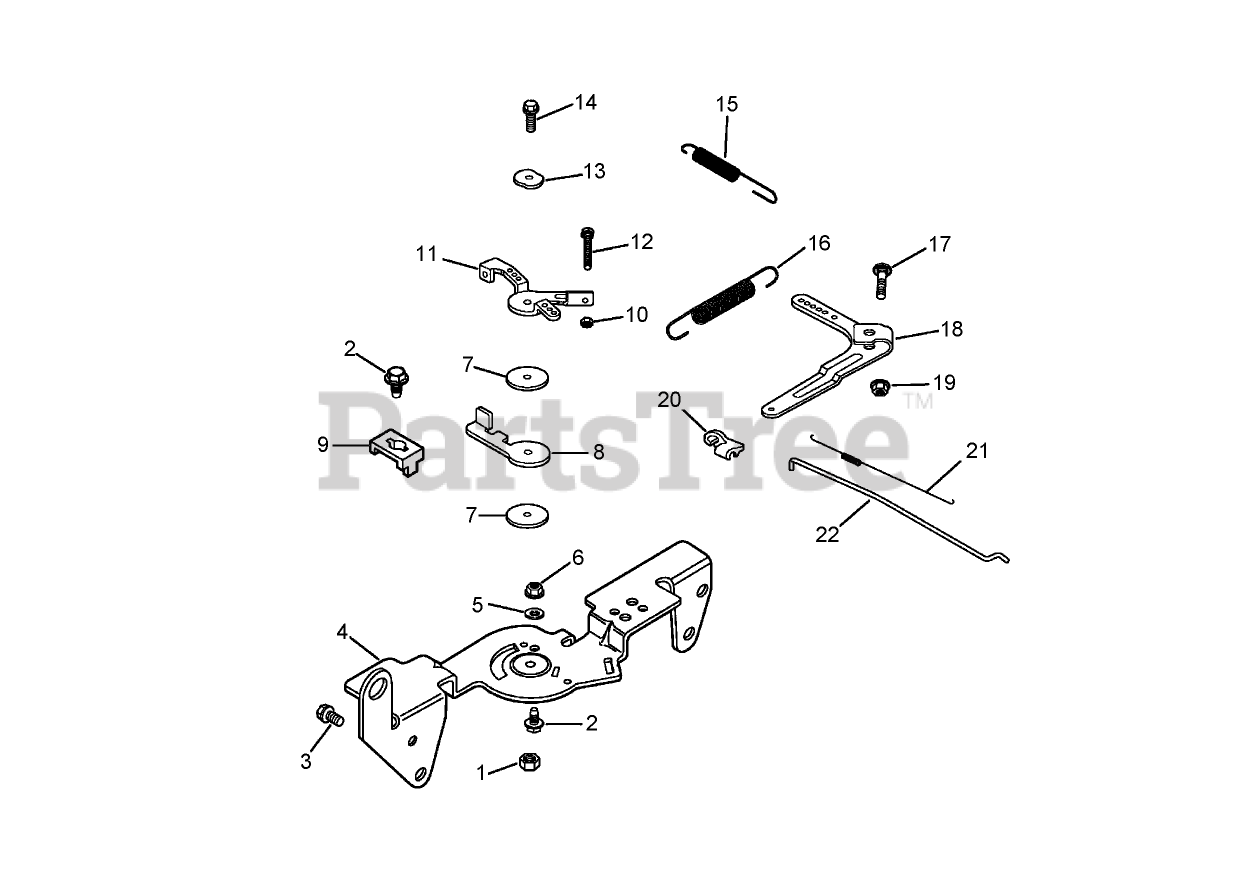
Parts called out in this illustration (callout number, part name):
1	NUT-LOCK (M5X.8)
2	SCREW-FLANGE, THREAD FORMING (M5X0.8X16)
3	SCREW-FLANGE, THREAD FORMING (M6X1.0X16)
4	Bracket-Control
5	Washer-Lock (.25)
6	Nut-HF (M5x0.8)
7	WASHER-FLAT (5.5MM)
8	Lever-Actuator, Throttle
9	CLAMP-CABLE
10	NUT (M4X0.7)
11	Lever-Control, Throttle
12	Screw (M4x0.7x30)
13	WASHER-SPRING (1/4)
14	SCREW-FLANGE, THREAD FORMING (M5X.8X20)
15	Spring-Limiter, Throttle
16	Spring-Governor
17	BOLT-SQ NECK, RD HD (M6X1.0X25)
18	Lever-Governor
19	NUT-FLANGE (M6X1.0)
20	BUSHING-RETAINING, LINKAGE
21	Spring-Linkage
22	Linkage-Throttle
